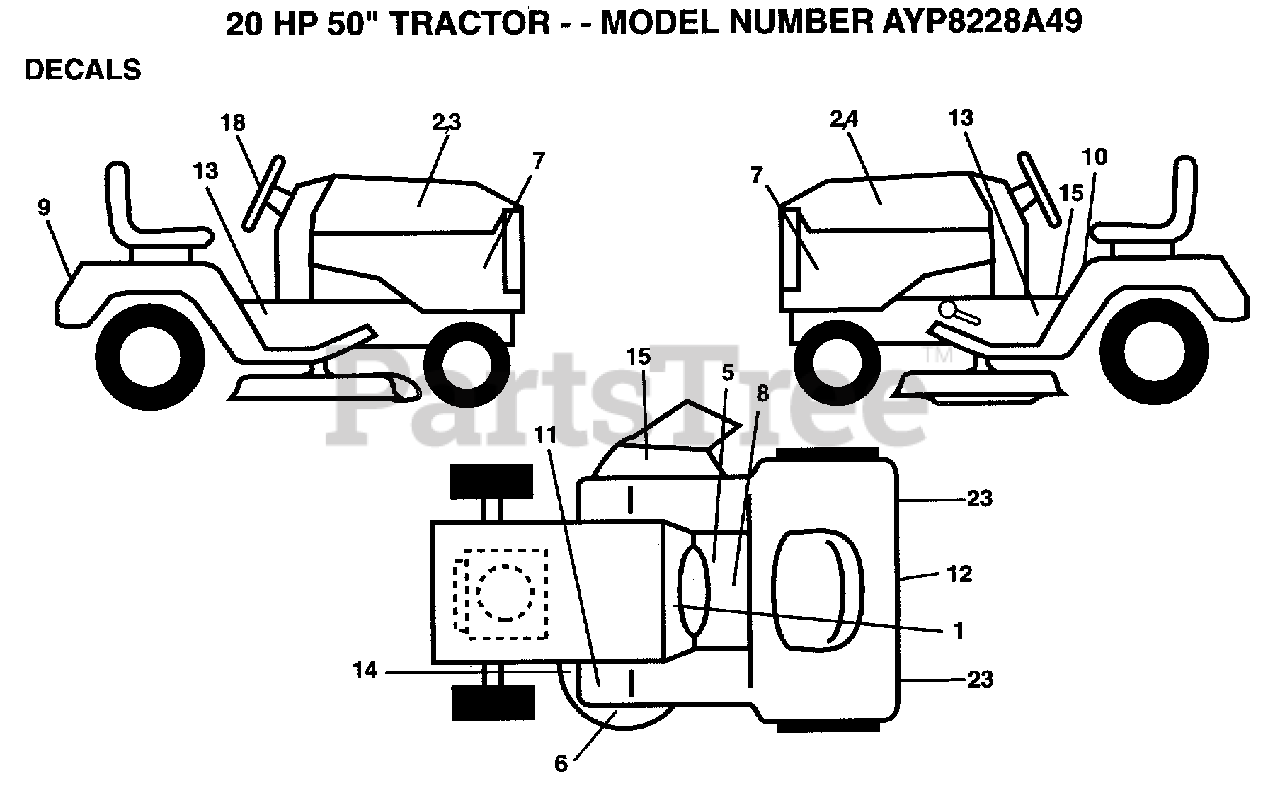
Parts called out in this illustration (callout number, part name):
1	DECAL.DASH.INST.
3	DECAL HD RH WIZ +
4	DECAL HD LH WIZ +
5	DECAL BRAK PARK
6	DECAL DECK WIZ +
7	DECAL PNL SD KOH
8	DECAL SADLE HYDRO
10	DECAL
12	DECAL D-BAR CNTRL
13	DECAL CHASSIS 50
14	"DECAL.V.BELT.44"""
15	"DECAL, WARNING"
18	DECAL INS STG WHL
23	REFLECTOR-TAIL YT
